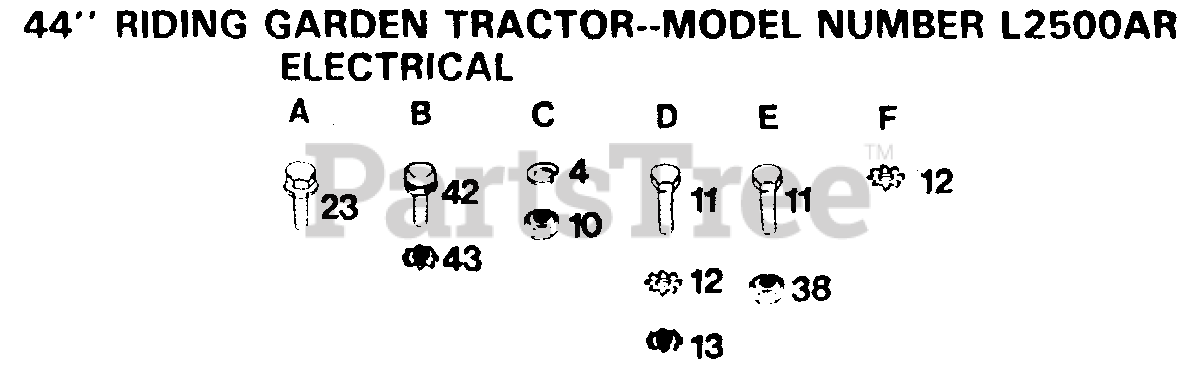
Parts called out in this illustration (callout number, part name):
10	NUT
11	BOLT
13	NUT
23	SCREW
42	SCREW
43	"NUT,KEPS"
